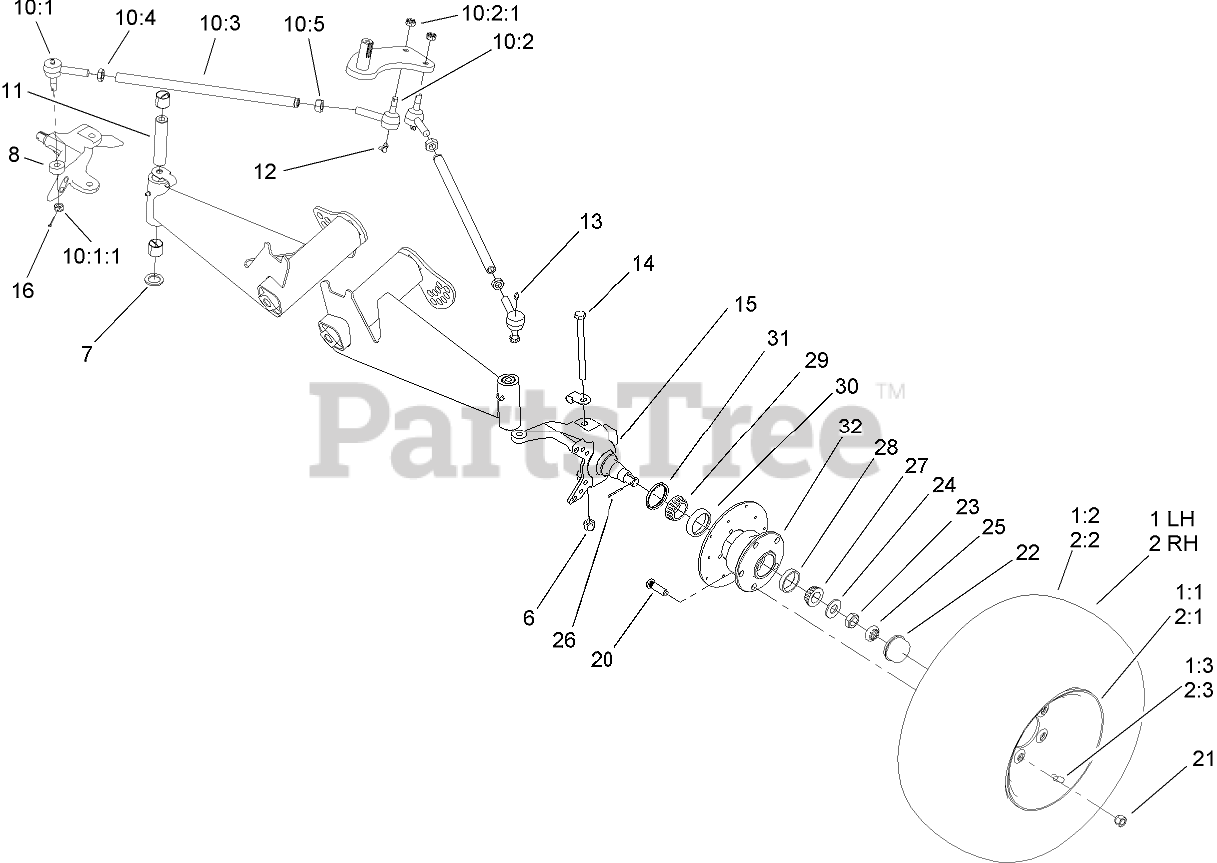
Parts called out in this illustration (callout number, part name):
1	TIRE AND WHEEL ASM
1:1	WHEEL-5 BOLT
1:3	STEM-VALVE
2	TIRE AND WHEEL ASM
2:1	WHEEL-5 BOLT
2:3	STEM-VALVE
6	NUT-LOCK, NI
7	WASHER-THRUST
8	SPINDLE-DISC, RH
10	Rod-Tie
10:1	JOINT-BALL, RH
10:2	JOINT-BALL, LH
10:3	ROD-TIE
10:4	NUT-JAM
10:5	NUT-JAM
11	SLEEVE-KINGPIN
12	FITTING-GREASE
13	FITTING-GREASE
14	SCREW-HH
15	SPINDLE-DISC, LH
16	PIN-COTTER
20	STUD-TYPE, DRIVE
21	NUT-LUG
22	CAP-DUST
23	NUT-JAM
24	WASHER-TAB
25	NUT-LOCK, RETAINER
26	PIN-COTTER
27	BEARING-CONE, TAPERED
28	BEARING-CUP, TAPERED
29	CONE-BEARING, TAPERED
30	CUP-BEARING, TAPERED
31	SEAL-SHAFT
32	HUB
